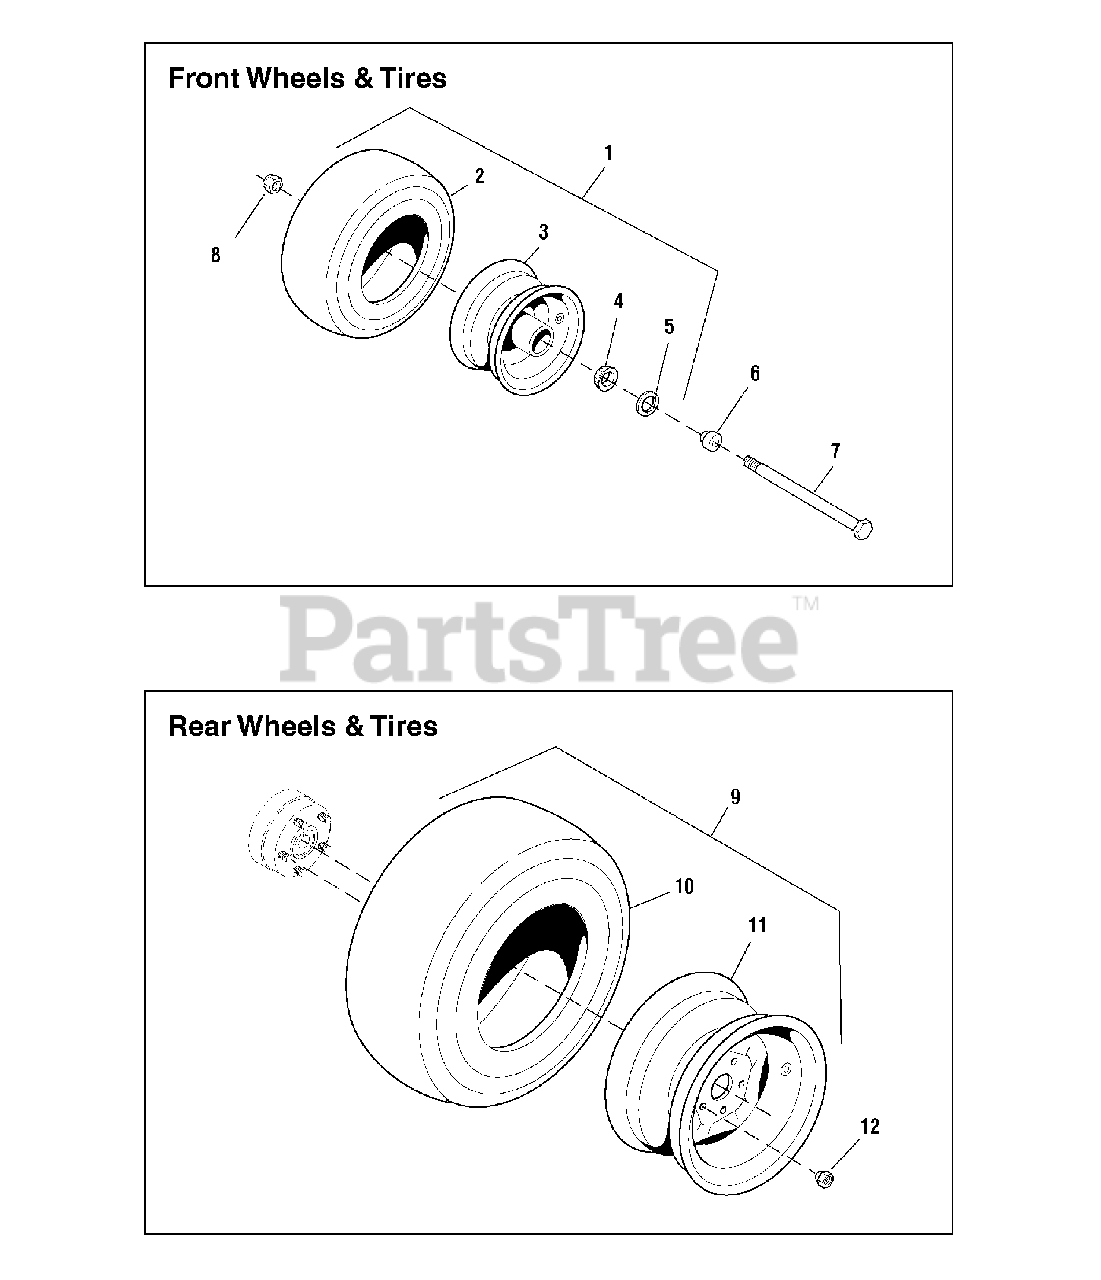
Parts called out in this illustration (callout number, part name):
1	WHEEL & TIRE ASSEMBLY, 13 x 5.0 - 6, Complete
1	* FLAT-FREE TIRE ASSEMBLY, 13 x 5.0 - 6 (Includes Ref No. 4 & 5)
2	TIRE, 13 x 5.0 -6
3	WHEEL ASSEMBLY, for 13 x 5.0 - 6 Tire, Complete
4	BEARING, TAPERED CONE
5	SEAL, GREASE
6	ADAPTER, Caster Wheel (2 per tire)
7	BOLT, 1/2-13 x 8"
8	NUT, 1/2-13 Hex Nylon Lock
9	WHEEL & TIRE ASSEMBLY, 22 x 11 - 10, Complete (Includes Ref No. 10 & 11)
10	TIRE, 22 x 11 - 10
11	WHEEL ASSEMBLY, 10 X 7
12	LUG NUT, 1/2-20
